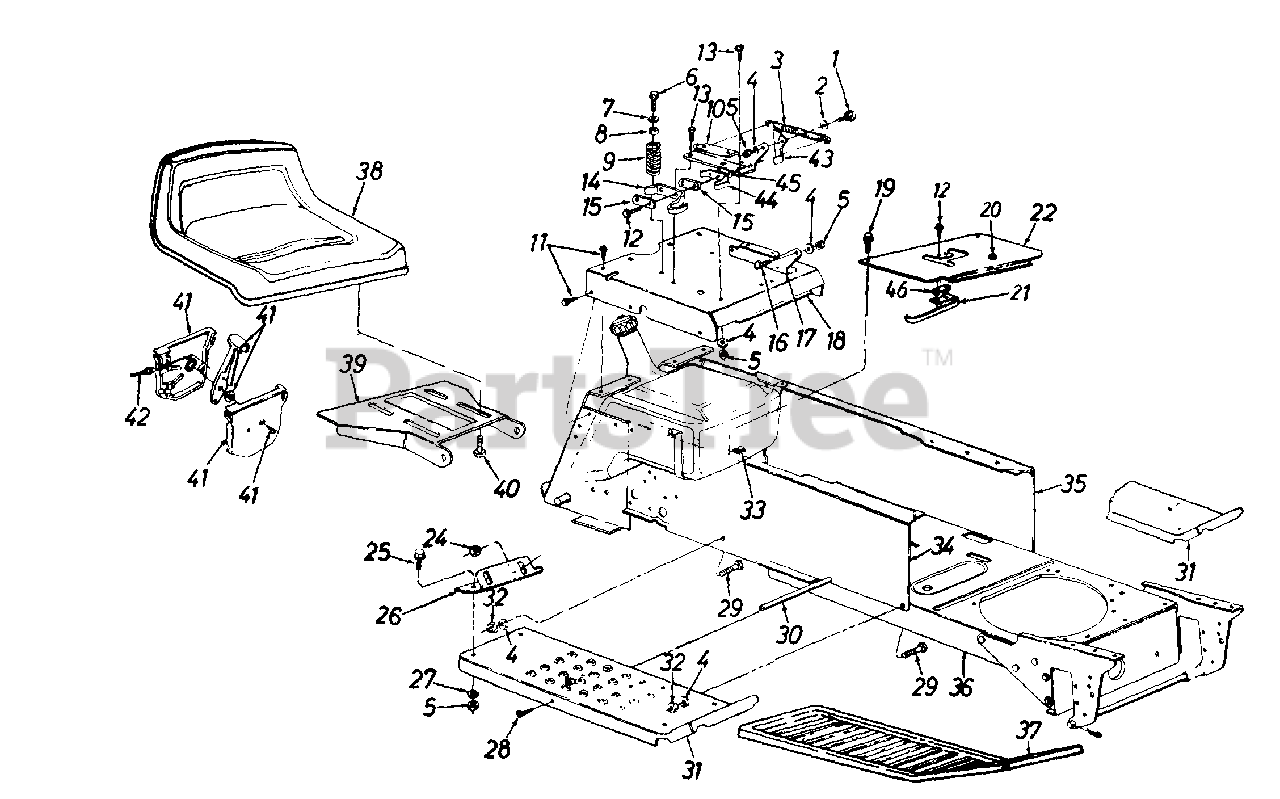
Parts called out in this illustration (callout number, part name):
1	Shld. Bolt .437" Dia. x .162"
2	Spr. Wash. .445" I.D.
3	Ext. Spring 5.31" Lg.
4	L-Wash. 5/16" I.D.
5	Hex Nut 5/16-18 Thd.
6	Hex Wash. Hd. Tap Scr. 5/16-18 x .7" Lg.
7	Fl-Wash. .344" I.D.
8	Bushing
9	Compression Spring
12	Hex Wash. Hd. AB-Tap Scr. #8 x .5" Lg.
13	Torx Hd. AB-Tap Scr. 5/16-18 x .75" Lg.
14	Spring Switch
15	Insulator Plate
16	Shld. Bolt .437" Dia. x .162"
19	Truss Mach. B-Tap Scr. #10 x .5" Lg.
20	Snap Bushing
21	Reverse Safety Switch
24	Hex Sems Nut 1/4-20
25	Hex Bolt 5/16-18 x .75" Lg.
28	Truss Mach. Scr. 5/16-18 x .75" Lg.
29	Rib Neck Bolt 5/16-24 x .75" Lg.
30	Running Board Rod
33	Speed Nut #10Z
38	Seat 8-7/8" High
40	Hex Tap Scr. 3/8-16 x .62" Lg.
41	Throttle Control Box Ass'y.
42	Throttle Control Wire 35" Lg.
43	Seat Lift Bracket
44	Seat Spring Switch
45	Insulator Boss Plate
46	Insulator Nut Plate
